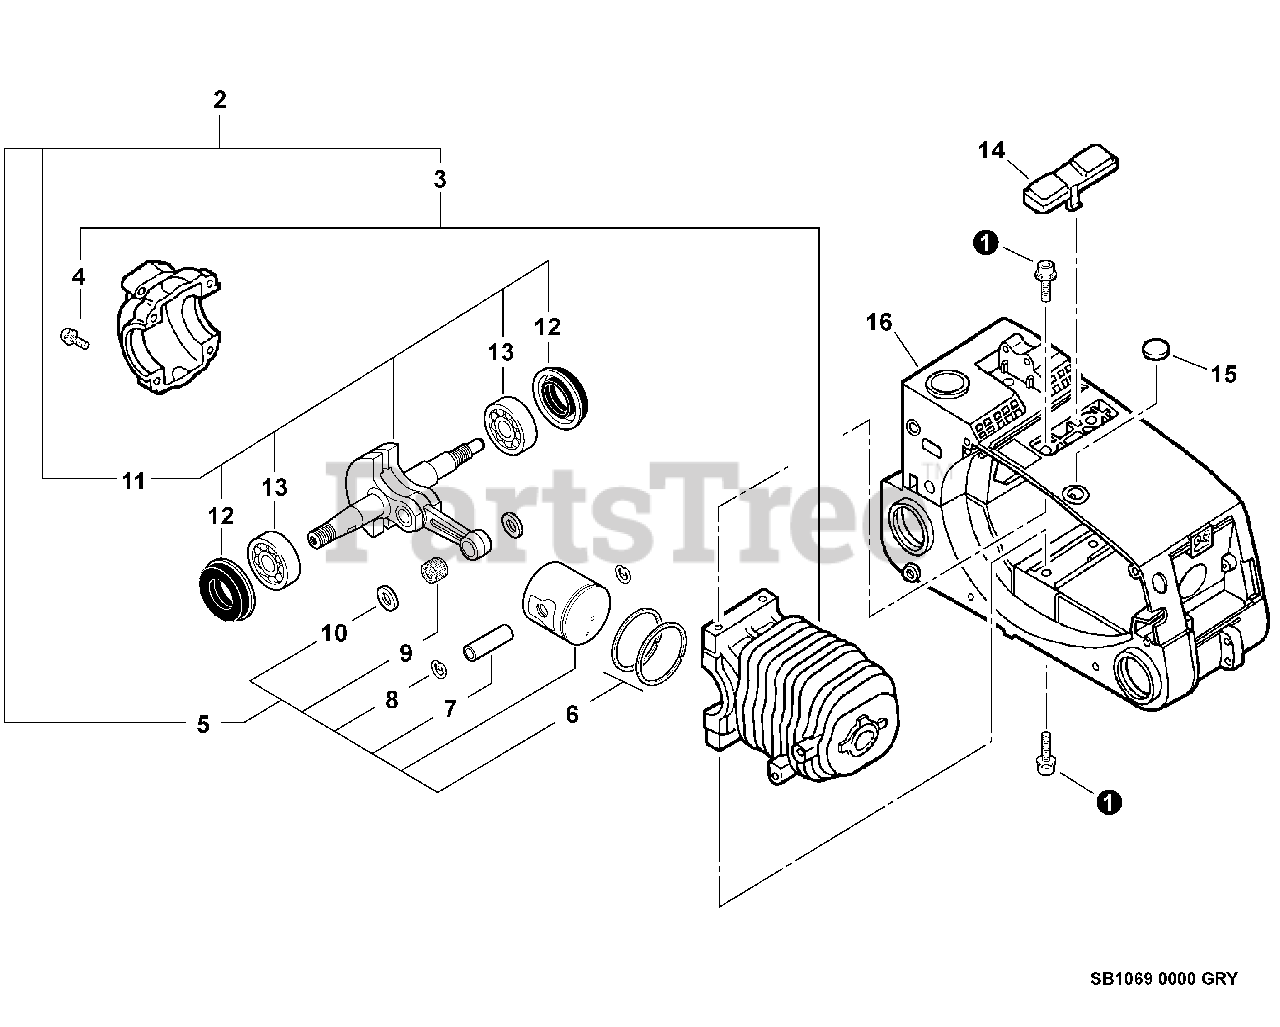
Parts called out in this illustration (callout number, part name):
1	SCREW - 5X16
2	SHORT BLOCK -- SB1069
3	CRANKCASE SET
4	SCREW - 5X25
5	PISTON KIT
6	RING, PISTON
7	PIN, PISTON
8	RING, RETAINING
9	BEARING, NEEDLE
10	SPACER, PISTON
11	CRANKSHAFT ASSY
12	SEAL, OIL - 12
13	BEARING, BALL - 6201
14	COVER - GRAY
16	COVER, ENGINE - GRAY
